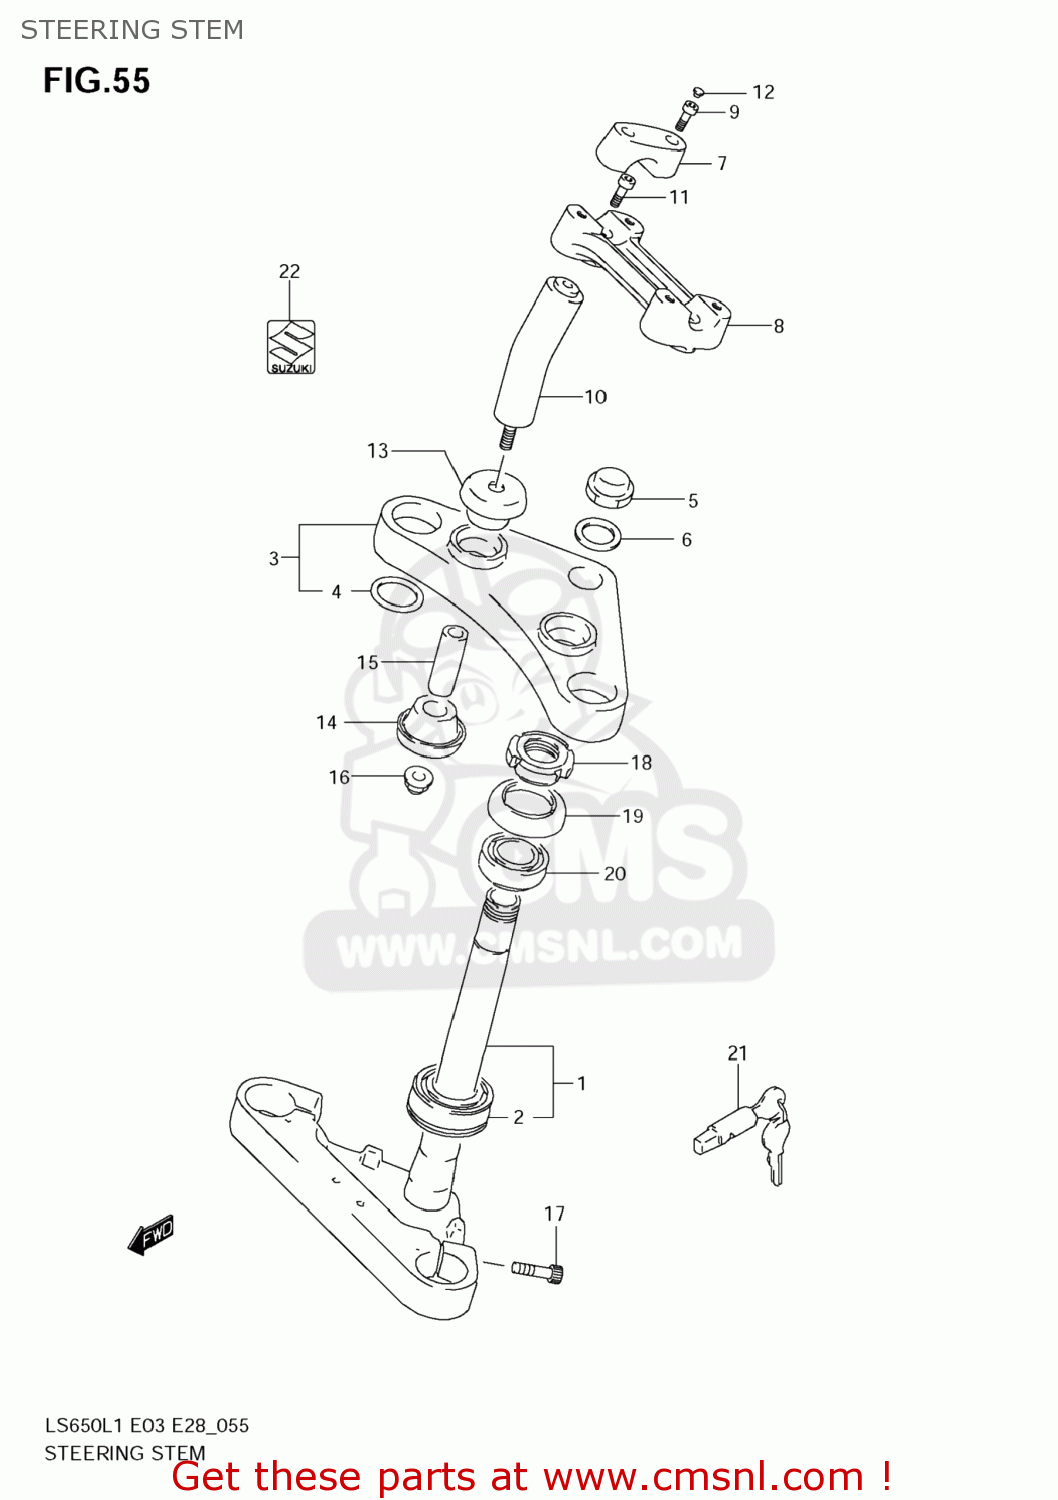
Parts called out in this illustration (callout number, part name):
1	STEM,STEERING
2	BEARING(30X55X17)
3	HEAD,STEERING STEM
4	WASHER,STEM HEAD,LOWER
5	NUT,CAP
6	WASHER(22.5X32X1.6)
7	HOLDER,HANDLE UPR
8	HOLDER,HANDLE LWR
9	BOLT
10	ARM
11	BOLT
12	CAP(OD:14.5)
13	CUSHION,UPR
14	CUSHION,LWR
15	SPACER(10.2X14X46)
16	NUT
17	BOLT
18	NUT,STEERING STEM(25X44X10)
19	SEAL,STEERING UPR DUST
20	BEARING(25X47X15)
21	LOCK ASSEMBLY,STEERING (NEI
22	EMBLEM,S
